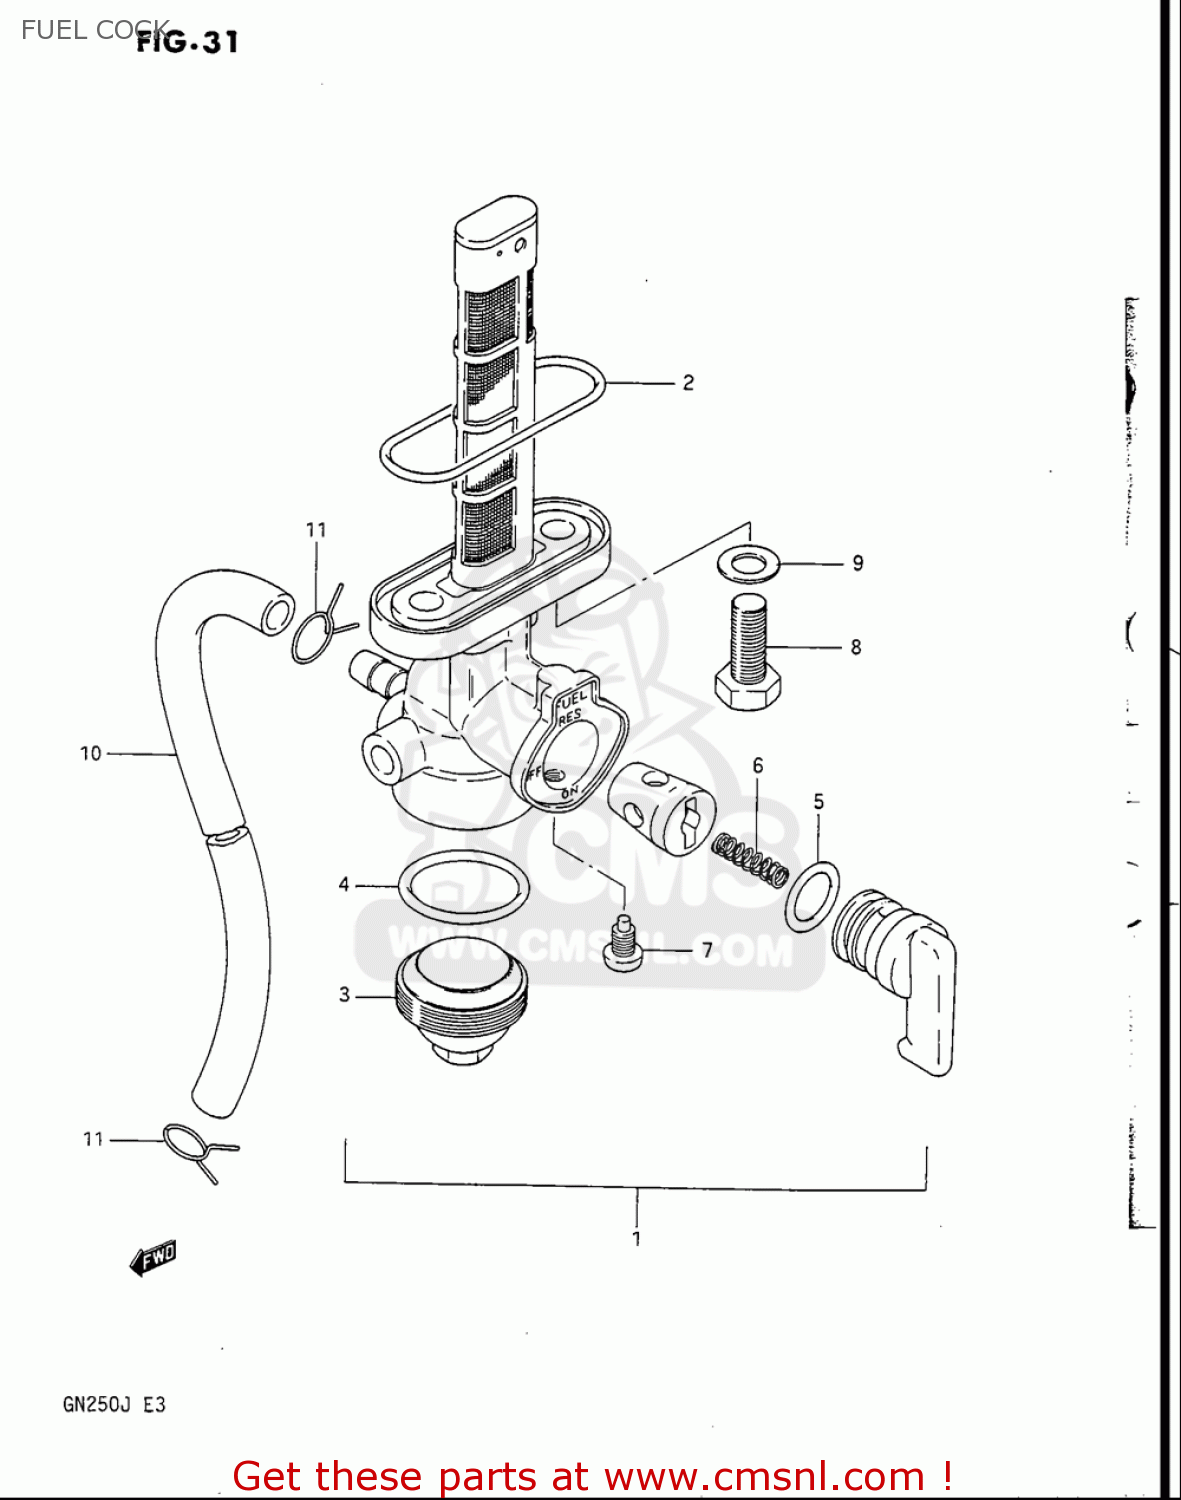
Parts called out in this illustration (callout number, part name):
1	COCK ASSY,FUEL
2	O RING,FUEL COCK
3	CUP,STRAINER
4	GASKET,FILTER (NAS)
5	O RING,LEVER
6	SPRING
7	SCREW
8	BOLT(6X20)
9	GASKET(5.8X13X1.2) (NAS)
10	HOSE(5X8.2X600)
11	CLIP
